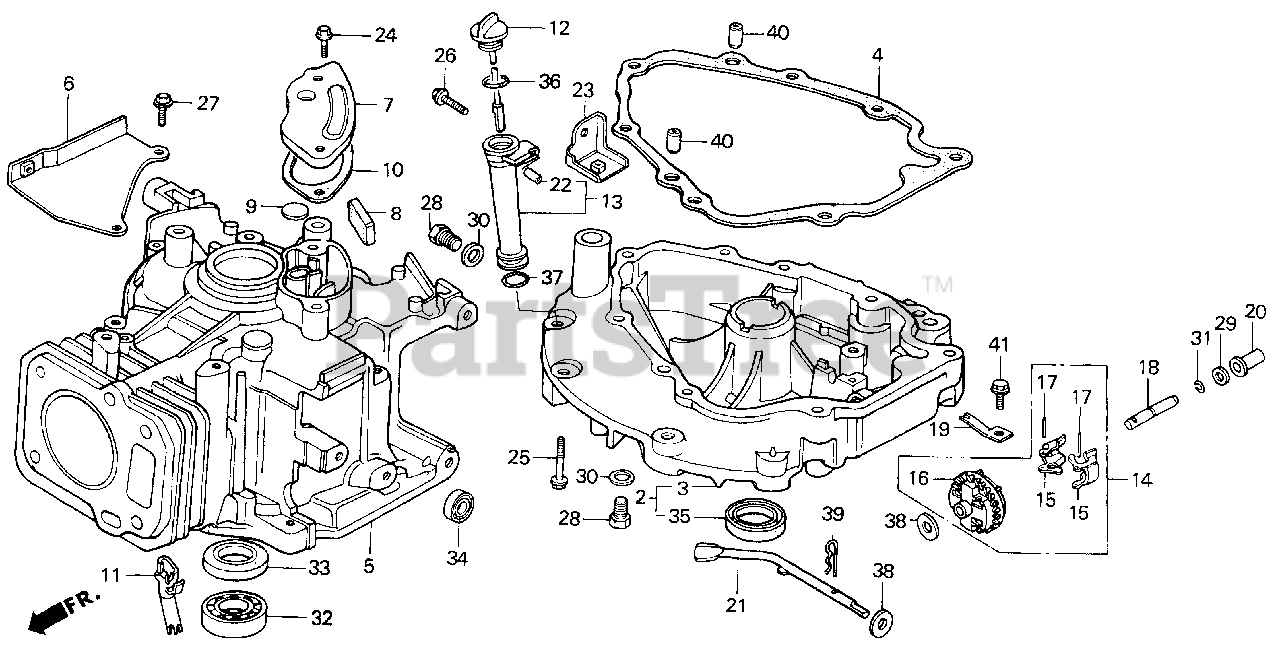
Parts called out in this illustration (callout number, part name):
2	PAN ASSY., OIL (NOT AVAILABLE)
4	GASKET, OIL PAN
4	GASKET, OIL PAN (HPE)
5	CYLINDER
7	CAP, BREATHER CHAMBER
8	FILTER, BREATHER
9	VALVE, BREATHER
10	GASKET, BREATHER CHAMBER
11	PIPE, OIL DEFENSE
12	DIPSTICK, OIL
13	EXTENSION, OIL FILLER (106MM)
14	GOVERNOR ASSY.
15	WEIGHT, GOVERNOR
16	HOLDER, GOVERNOR WEIGHT
17	PIN, GOVERNOR WEIGHT
18	SHAFT, GOVERNOR HOLDER
19	PLATE, GOVERNOR SHAFT HOLDER
20	SLIDER, GOVERNOR
21	SHAFT, GOVERNOR ARM
22	COLLAR, EXTENSION
23	BASE, HOLDER
24	BOLT, FLANGE (6X12) (CT200)
25	BOLT, FLANGE (6X28)
26	BOLT, FLANGE (6X32)
28	BOLT, DRAIN PLUG
29	WASHER, THRUST (6MM)
30	WASHER, DRAIN PLUG (10.2MM)
31	CLIP, GOVERNOR HOLDER
32	BEARING, RADIAL BALL (62/22)
33	OIL SEAL (22X35X6)
34	OIL SEAL (6X11X4)
35	OIL SEAL (25X38X7)
35	OIL SEAL (25X38X7) (ARAI)
36	O-RING (26X2.7)
37	O-RING (22.5X2.2)
38	WASHER, PLAIN (6MM)
39	PIN, LOCK (8MM)
40	PIN A, DOWEL (8X14)
41	BOLT, FLANGE (6X12)
